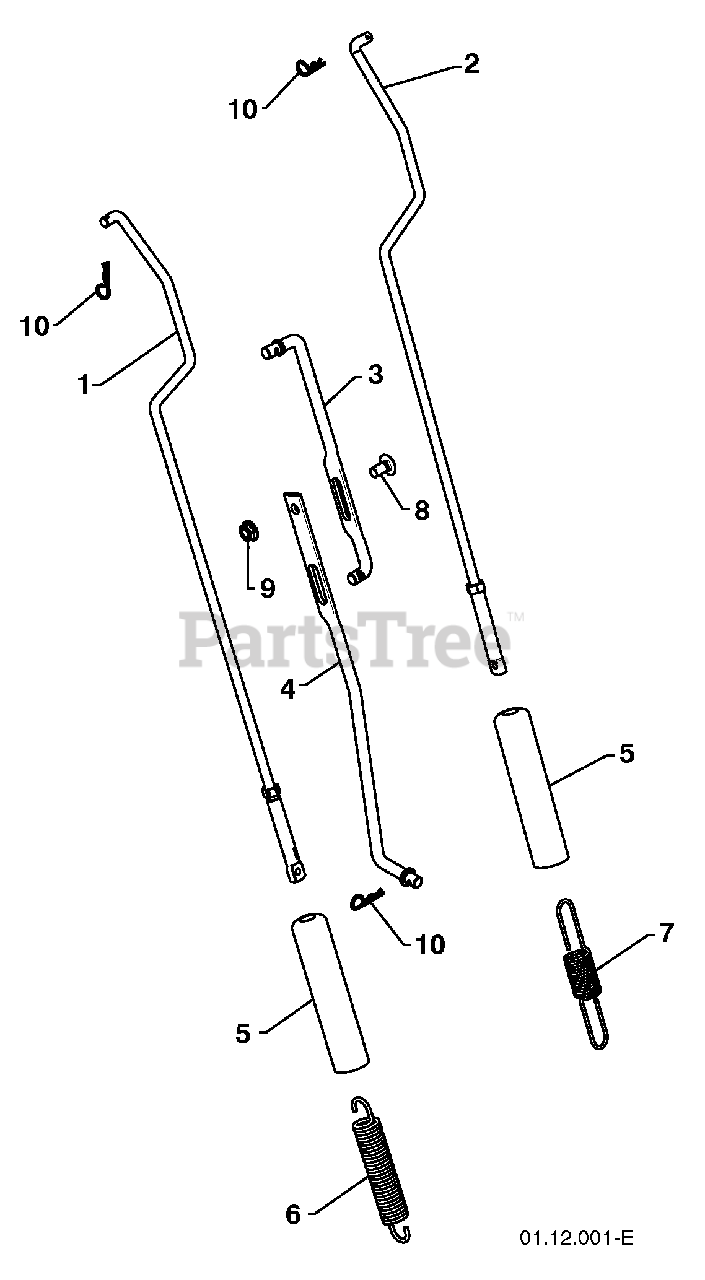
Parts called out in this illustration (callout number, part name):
1	IMPELLER ROD
2	TRACTION ROD
3	SHIFTER ROD TOP
4	SHIFTER ROD BOTTOM
5	SPRING SLEEVE
6	IMPELLER SPRING
7	TRACTION SPRING
8	CARRIAGE BOLT 5/16-18 X .625
9	NUT 5/16-18
10	RETAINER
